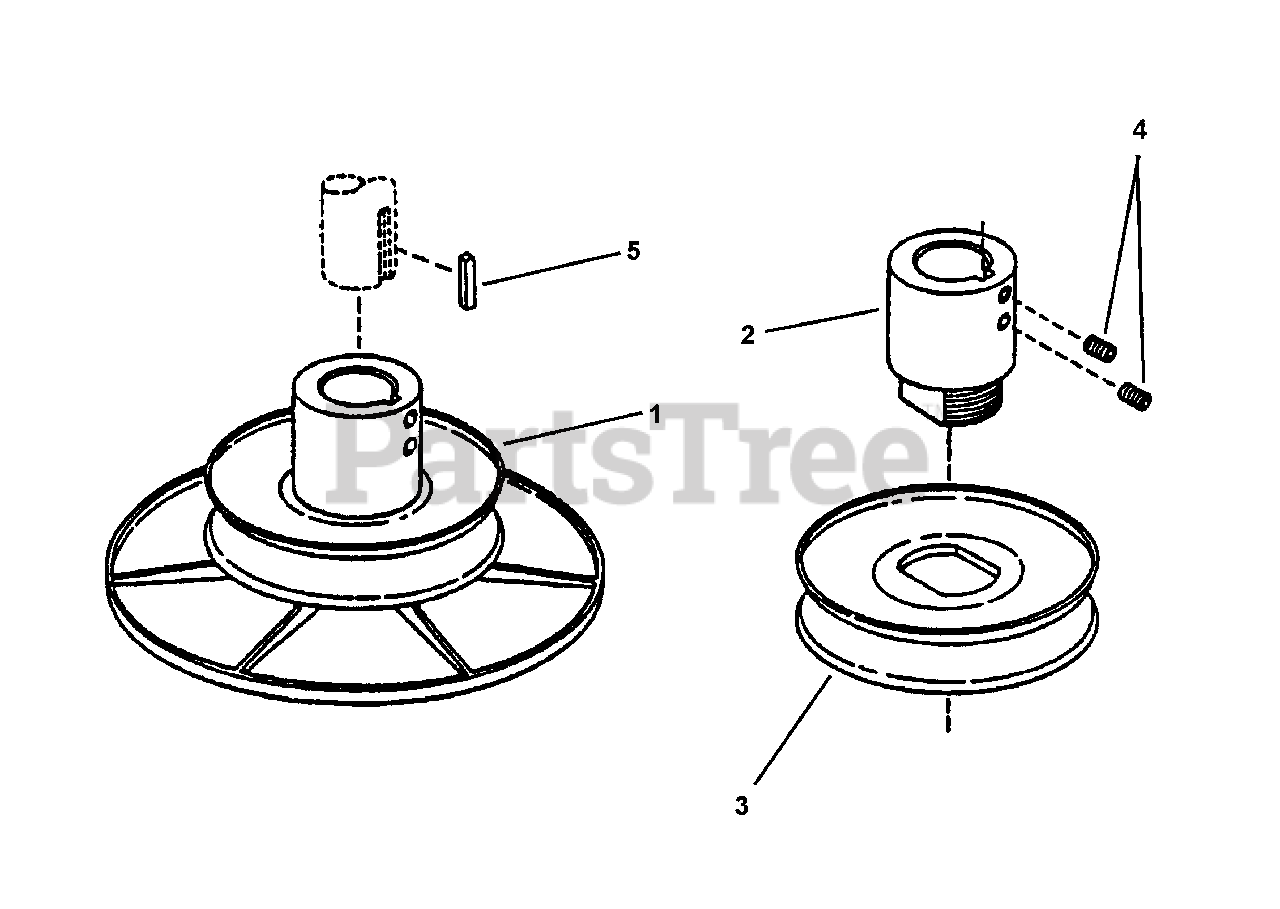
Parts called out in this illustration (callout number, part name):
1	ASSEMBLY, 5.18" O.D. Drive Disc (Was 53708)
3	PULLEY, Drive (5.75" O.D.)
4	SCREW, 3/8-16 x 3/8" Set
5	KEY, 1/4" Square x 2"
